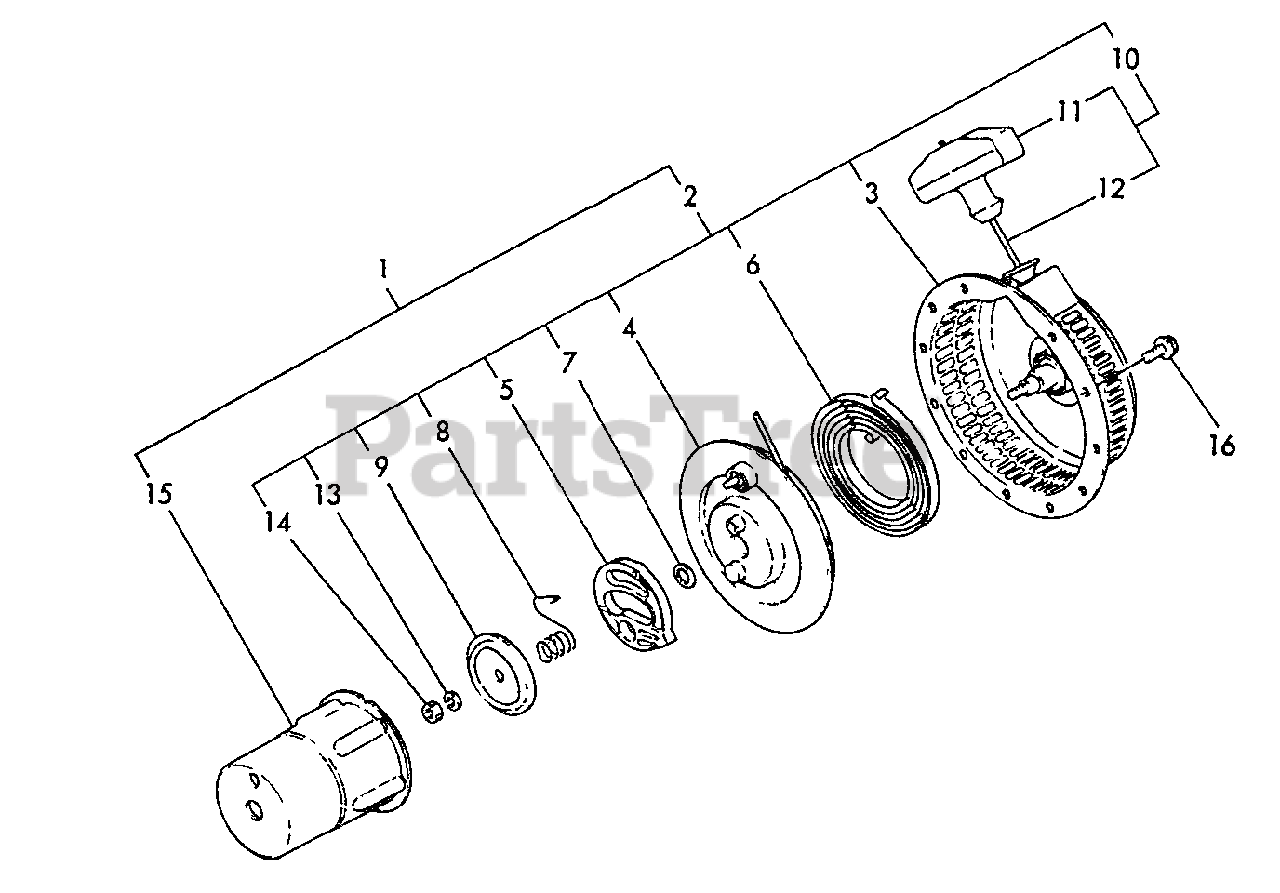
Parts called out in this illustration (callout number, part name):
1	STARTER ASSY
2	STARTER ASSY
3	CASE, STARTER
4	PULLEY
7	WASHER, THRUST
8	SPRING, FRICTION
9	PLATE, FRICTION
10	STARTER ROPE ASSY
11	GRIP, STARTER
12	ROPE, STARTER
13	LOCKWASHER - 6
14	NUT - 6
15	PULLEY, STARTER
16	BOLT - 6X8 -- PLATED
